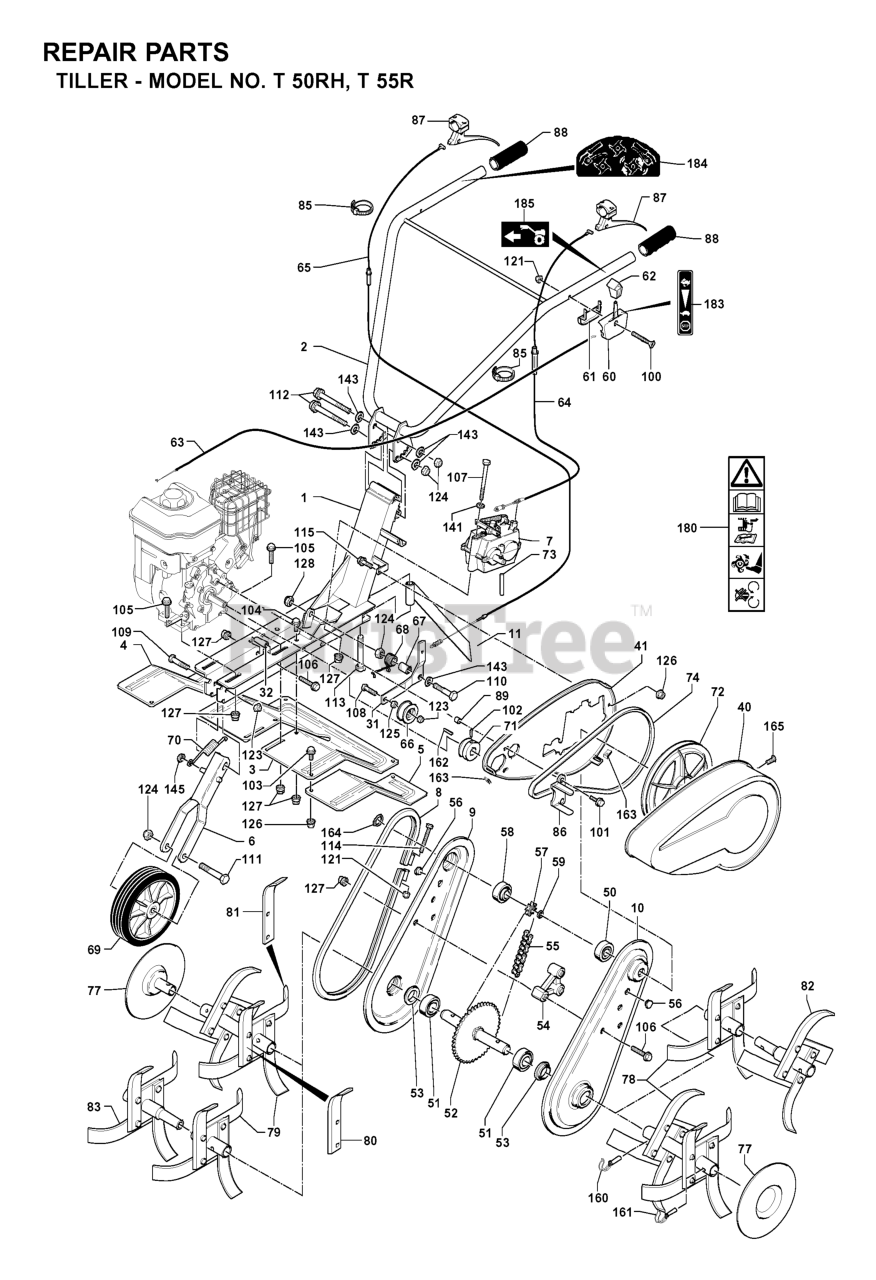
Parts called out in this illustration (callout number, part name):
1	DECK W/DECALS 61" HUS
2	FOOTREST ORANGE
3	ANTI-SKID PAD
4	KNOB W/STUD
5	FOOT PLATE
6	GROMMET, BUMPER
7	CONSOLE WLD
8	FUEL CAP
10	STUD, 5/16C
11	FUEL TANK RT
12	U-CLIP 5/16-18 NUT RETAINER
13	WASHER.LOCK.HVY.HLCL.SPR.5/16
14	NUT 5/16 NYLOC
15	HCS 5/16C X 1
16	SKID PLATE
17	ENGINE GUARD
18	ENGINE SHROUD BRKT
20	STRUT MOUNT WELDMENT
21	STRUT, RIGHT
23	HYDRAULIC CAP
24	BATTERY HOLD DOWN
25	WASHER 1/4 FLAT
26	HCS 1/4C X 3/4 HCS
27	SEAT BRKT W/DECAL
28	IGNITION SWITCH KIT
29	WASHER 5/16 FLAT
31	WASHER 1/4 FLAT
32	DIGITAL HOUR METER
33	HCS 1/4C X 3/4 HCS
34	SCREW 1/4 X 5/8
35	LOCKWASHER 1/4"
36	RP.SWITCH, BLADE
37	STUD/PLATE MOUNT
38	TANK MOUNT
39	TANK MOUNT
40	NUT.1/4-20.HEX.NYLOC.ZD
42	HCS 5/16C X 3/4
43	NUT 5/16C CENTERLOCK
45	RHSSNB 5/16C X 1.0
46	HCS 5/16C X 4
47	CHOKE CONTROL, COMPLETE
539102650	HOSE BARB 90 DEGREE
539102679	FUEL VALVE
539103275	THROTTLE CABLE
539104409	LEFT TANK W/CUP HOLDER
539105281	FUEL LINE 29.5"
539105527	FUEL LINE 24"
539105530	FUEL LINE 34"
539108351	STRUT, LEFT
539912222	HOSE CLAMP
